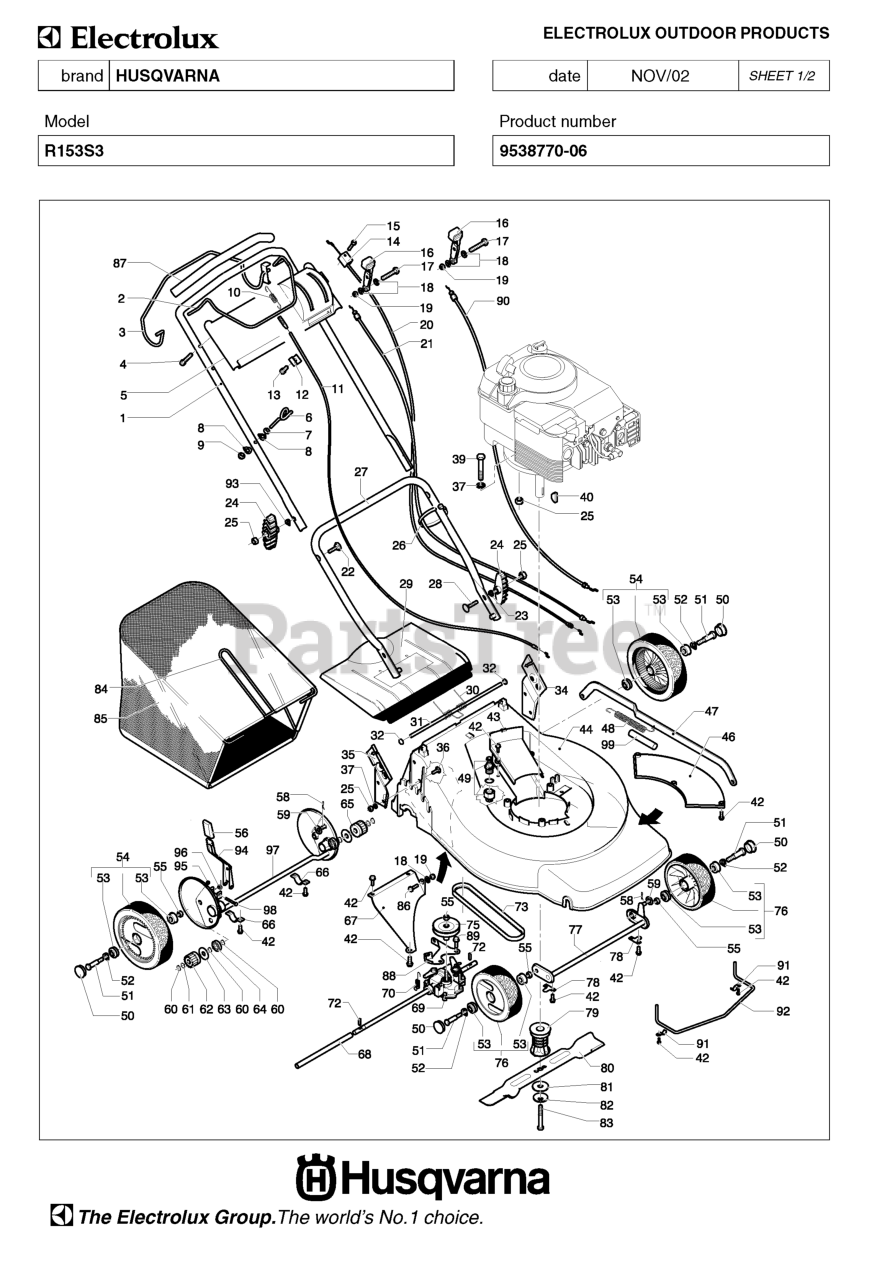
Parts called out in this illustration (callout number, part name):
28	Screws
42	Screws
58	Pins
60	Washers
